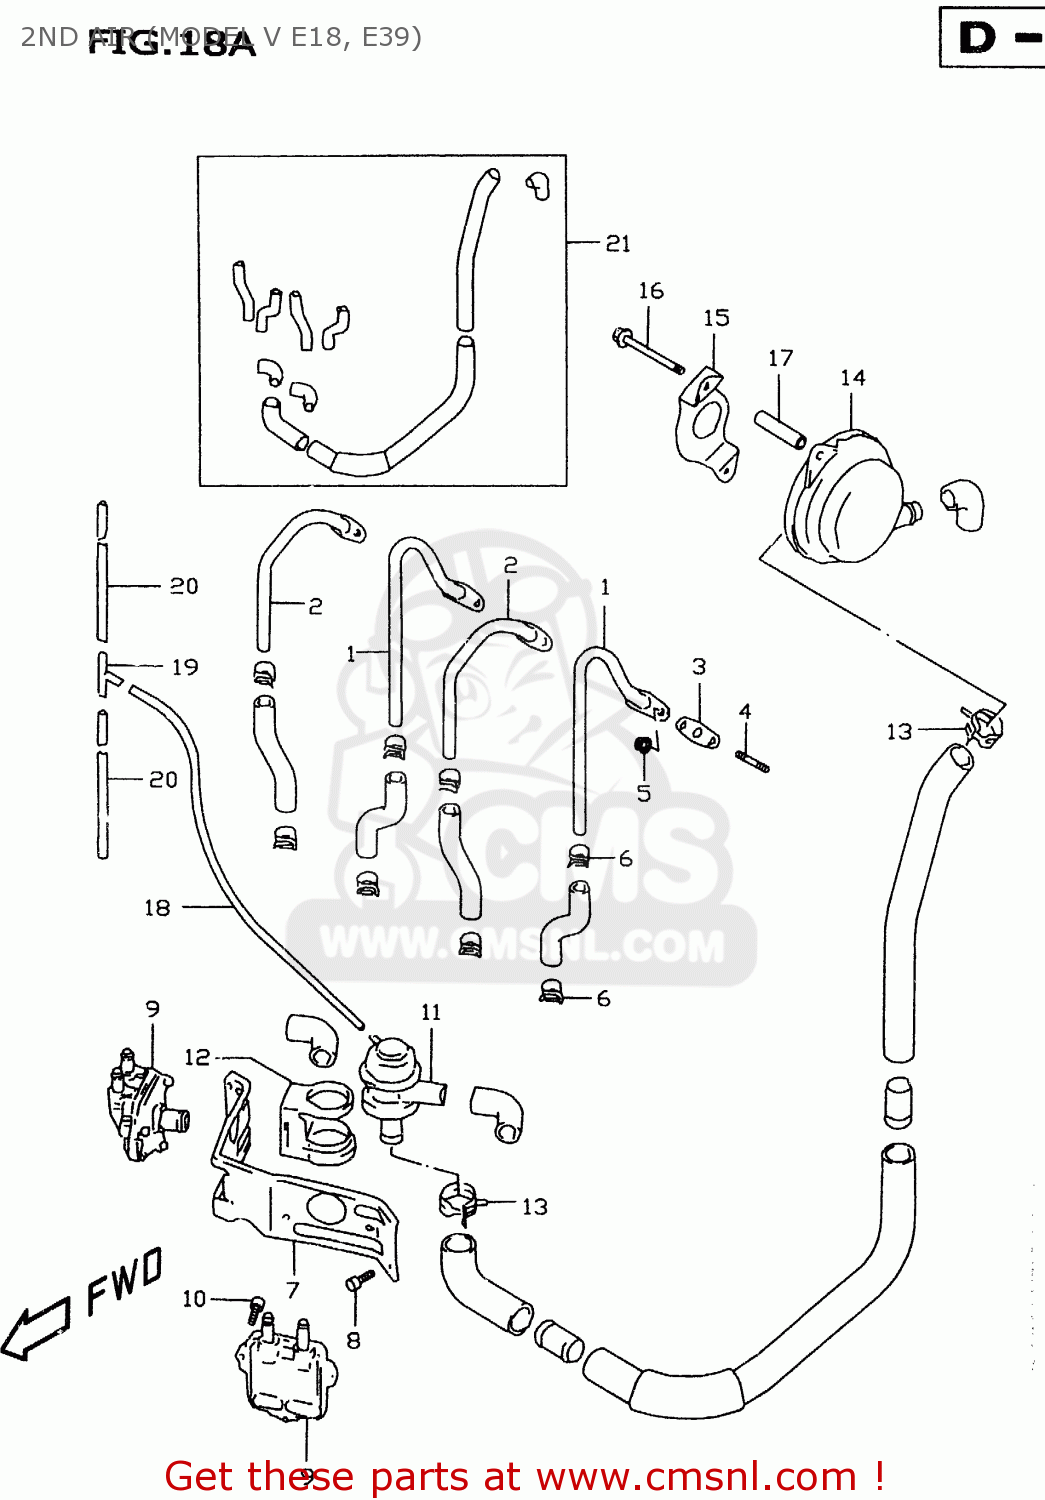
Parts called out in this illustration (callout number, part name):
1	PIPE COMP,SECOND AIR NO.1
2	PIPE COMP,SECOND AIR NO.2
3	GASKET,SECOND AIR PIPE (N (NAS)
4	STUD BOLT
5	NUT
6	CLIP
7	BRACKET COMP,SECOND AIR
8	BOLT 6X12
9	VALVE ASSY,2ND AIR REED
10	BOLT
11	VALVE ASSEMBLY,SECOND AIR SWITCH
12	CUSHION,2ND AIR VALVE
13	CLAMP
14	CLEANER ASSEMBLY,SECOND AIR
15	HOLDER,SECOND AIR CLEANER
16	BOLT
17	SPACER(6.5X10.5X40)
18	HOSE(4X7X600)
19	JOINT,3 WAY
20	HOSE(5X10X600)
21	HOSE SET,2ND AIR
